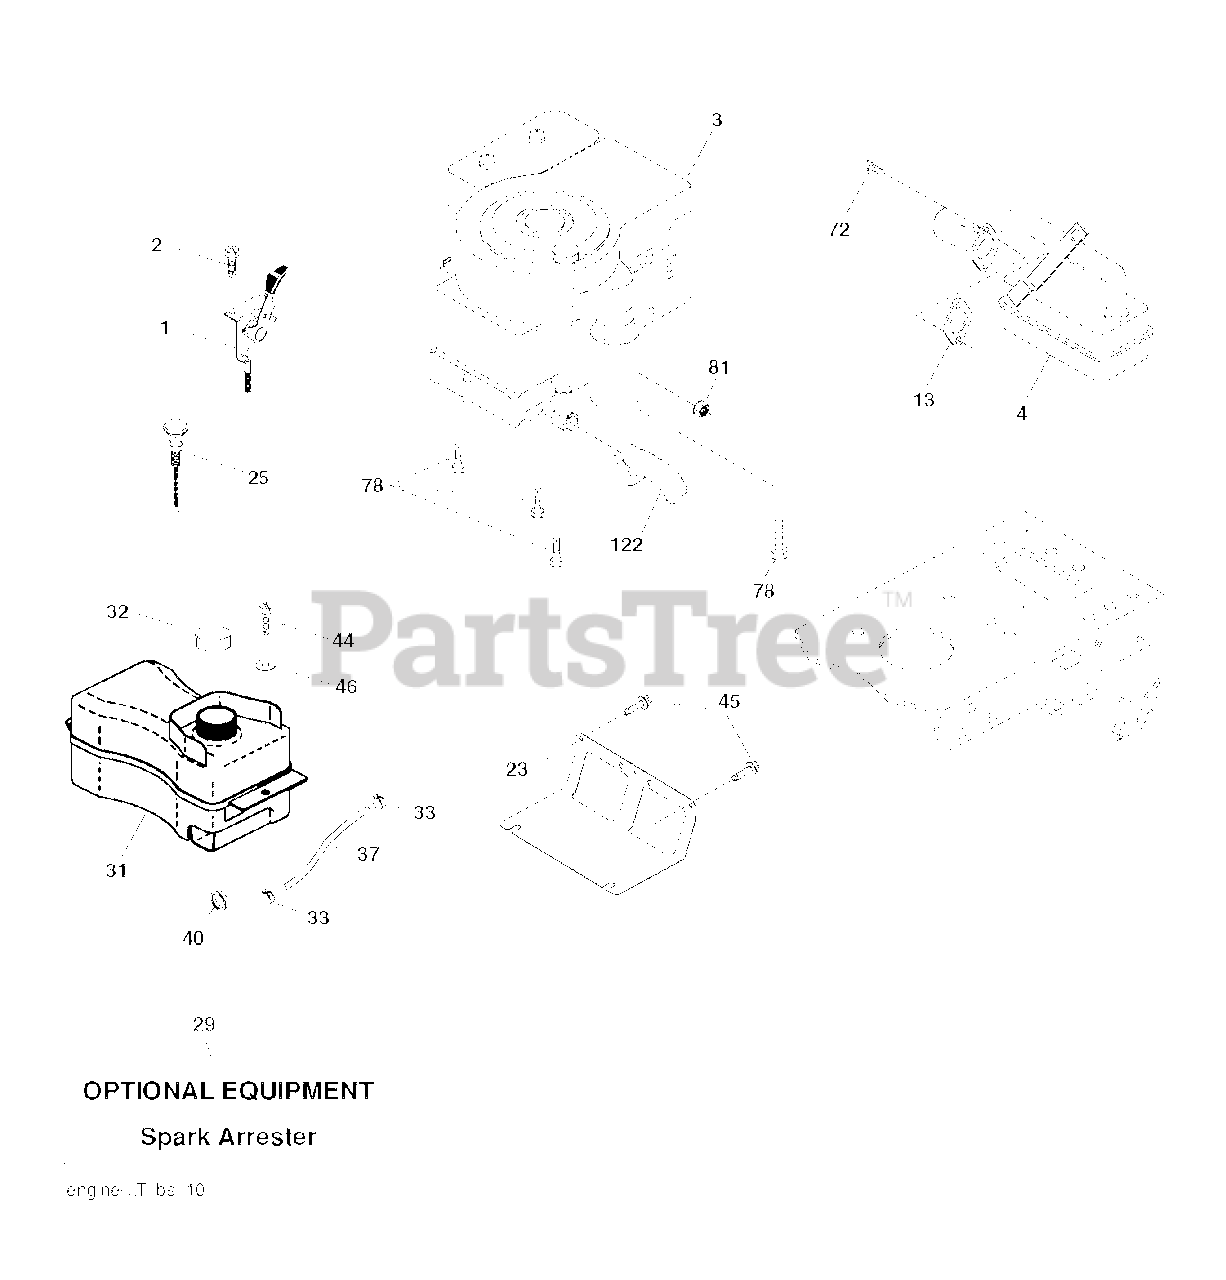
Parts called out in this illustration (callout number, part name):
1	CONTROL TH/CH FLAG
2	SCREW
13	REPL BY 532 27 22-93
23	SHEILD.BROWNING.DBR.GUARD
29	ARRESTER SPARK (OPTIONAL)
31	TANK ASM.FRONT.1.25GA
32	CAP ASM.FUEL.2.25"FR.
33	HOSE CLAMP
37	LINE.FUEL.20
40	GROMMET T
44	SCREW HEXWSHR 1/4-20X3/4
45	SCREW, 3/8-16X3/4
72	SCREW.SOCKET HD.5/16-1
78	SCREW.3/8-16
81	NUT
122	EXTENSION DRAIN OIL
